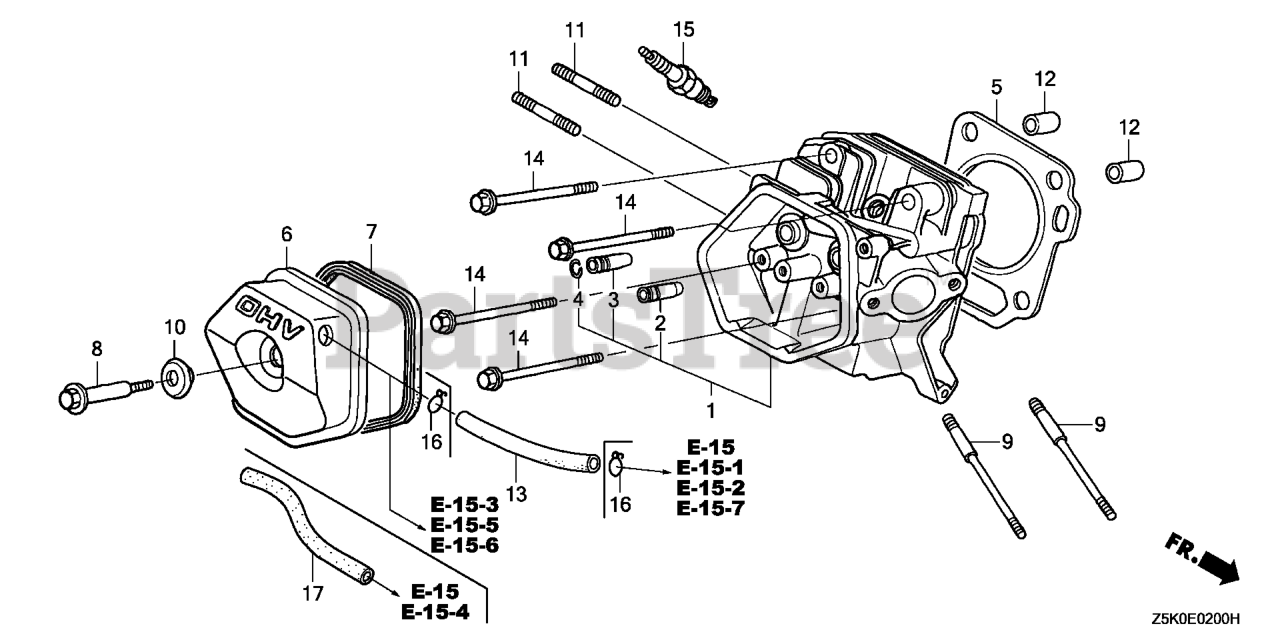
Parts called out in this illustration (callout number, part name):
1	CYLINDER HEAD
4	CLIP, VALVE GUIDE
5	GASKET, CYLINDER HEAD
6	COVER, HEAD
6	COVER, CYLINDER HEAD
7	GASKET, CYLINDER HEAD COVER
8	BOLT, HEAD COVER
9	BOLT, STUD (8X123)
10	WASHER, HEAD COVER
11	BOLT 2, STUD (8X32)
12	PIN A, DOWEL (12X20)
14	BOLT, FLANGE (10X80)
15	SPARK PLUG (BPR5ES) (NGK)
15	SPARK PLUG (W16EPR-U) (DENSO)
15	SPARK PLUG (BPR6ES) (NGK)
17	TUBE, BREATHER
